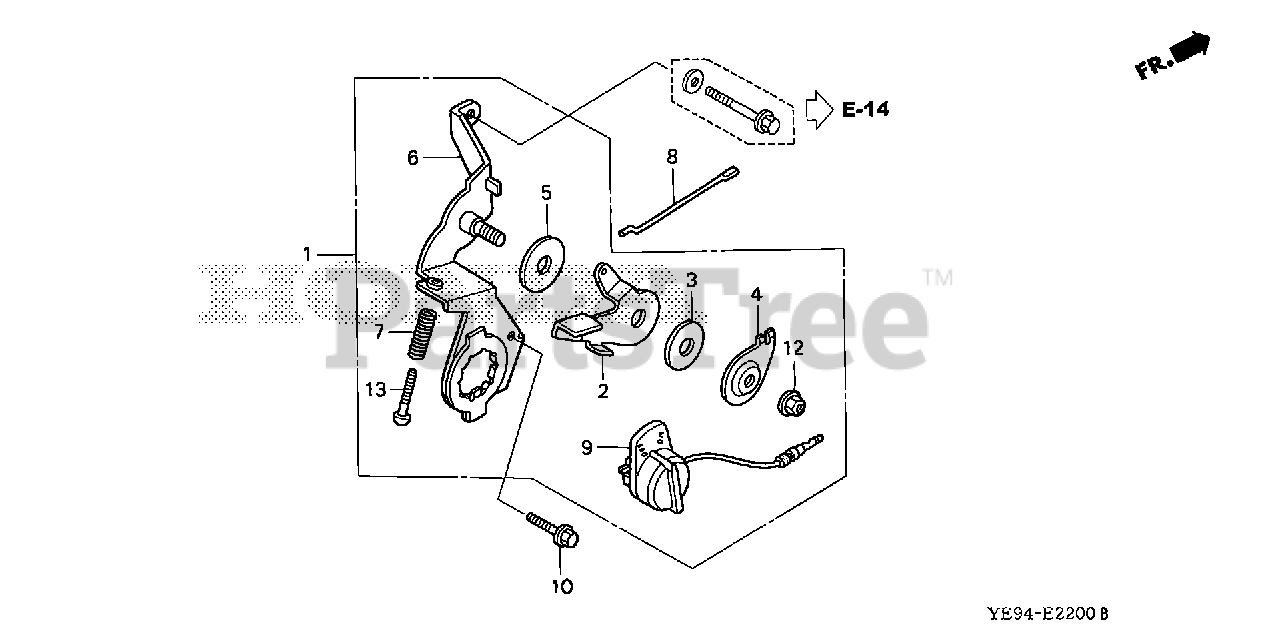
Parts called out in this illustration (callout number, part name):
1	CONTROL ASSY. (NOT AVAILABLE)
1	CONTROL ASSY.
2	LEVER, CONTROL (NOT AVAILABLE)
3	SPRING, LEVER
4	WASHER, CONTROL LEVER
5	SPACER, CONTROL LEVER
6	BASE, CONTROL
7	SPRING, CONTROL ADJUSTING
8	ROD, THROTTLE
9	SWITCH ASSY., ENGINE STOP
10	BOLT, FLANGE (5X16)
12	NUT, SELF-LOCK (6MM)
13	SCREW, PAN (5X25)
